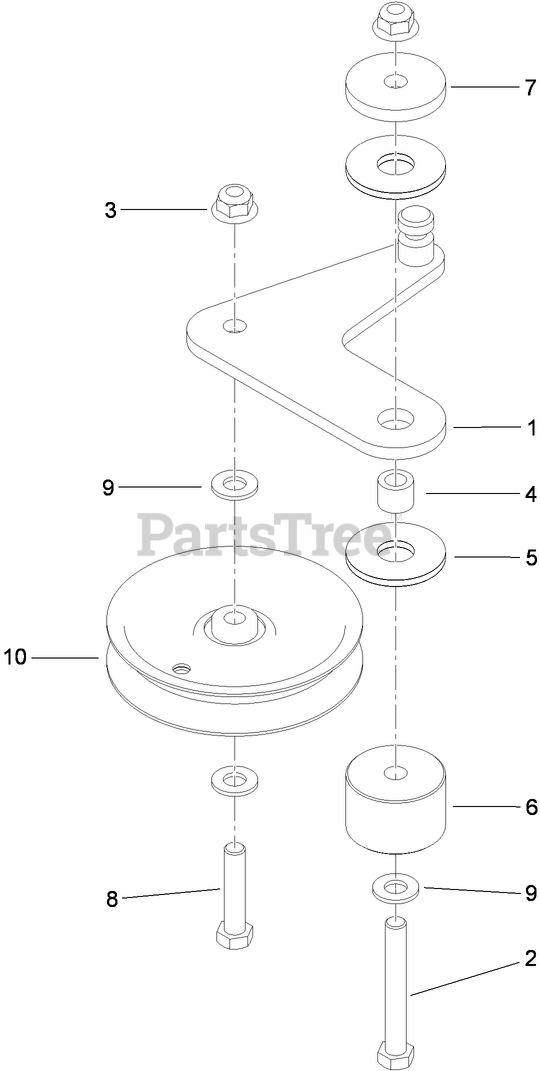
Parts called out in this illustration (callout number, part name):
1	PLATE-IDLER
2	SCREW-HH
3	NUT-HF, NI
4	BUSHING-LEVER, LIFT
5	WASHER-FRICTION, COMPOSITE
6	HUB-IDLER
7	WASHER-PLAIN
8	SCREW-HH
9	WASHER-FLAT
10	PULLEY-IDLER
